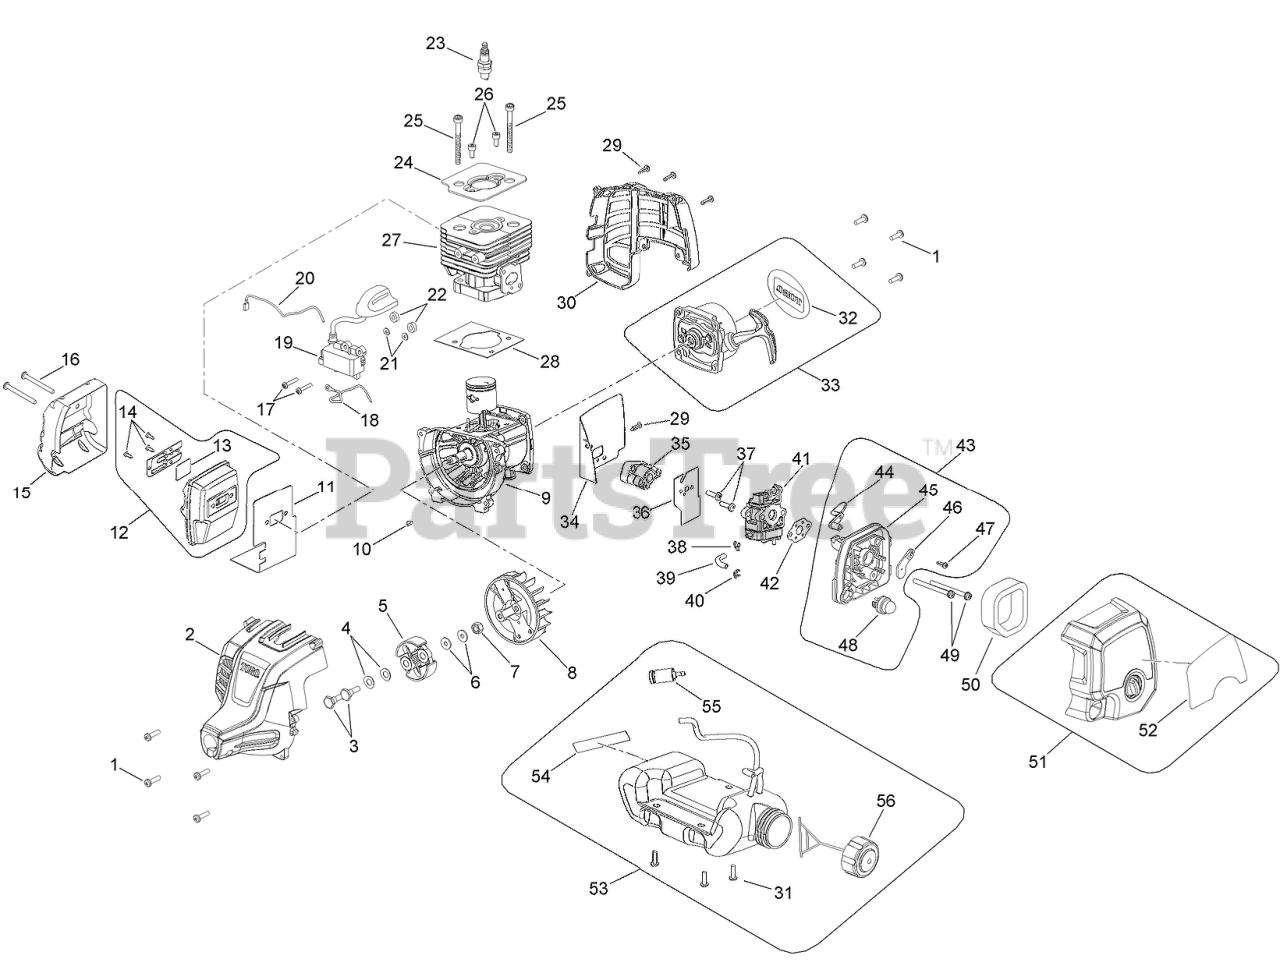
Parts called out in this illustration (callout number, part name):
1	SCREW-PH
2	HOUSING-ENGINE, FRONT
3	SCREW-CLUTCH
4	WASHER-CURVED
7	NUT-ROTOR
9	CRANKCASE ASM
10	KEY-WOODRUFF
11	GASKET-MUFFLER
12	MUFFLER ASM
14	SCREW-PH
15	SHIELD-HEAT
16	SCREW-PH
17	SCREW-PH
18	WIRE-LEAD, RED
19	COIL BOOT ASM
20	WIRE-LEAD, BLACK
23	SPARK PLUG
24	PLATE-CYLINDER
25	SCREW-SOCKET HEAD
26	SCREW-PH, TORX
27	CYLINDER
30	HOUSING-ENGINE, REAR
32	PLATE-LOGO
33	RECOIL STARTER AND STARTER CUP ASM
35	INSULATOR-DAM, HEAT
37	SCREW-PH
38	CLIP-HOSE
39	LINE-FUEL
40	CLIP-HOSE
41	CARBURETOR ASM
43	FILTER HOUSING ASM
44	LEVER-CHOKE
45	PLATE-CARBURETOR
46	PLATE-CHOKE
47	SCREW-PH
48	PRIMER ASM
49	SCREW-PH
50	ELEMENT-FILTER, AIR
51	COVER ASM
52	DECAL-START
53	FUEL TANK AND CAP ASM
54	LABEL-COMBUSTION
55	FILTER-FUEL
56	CAP-FUEL
